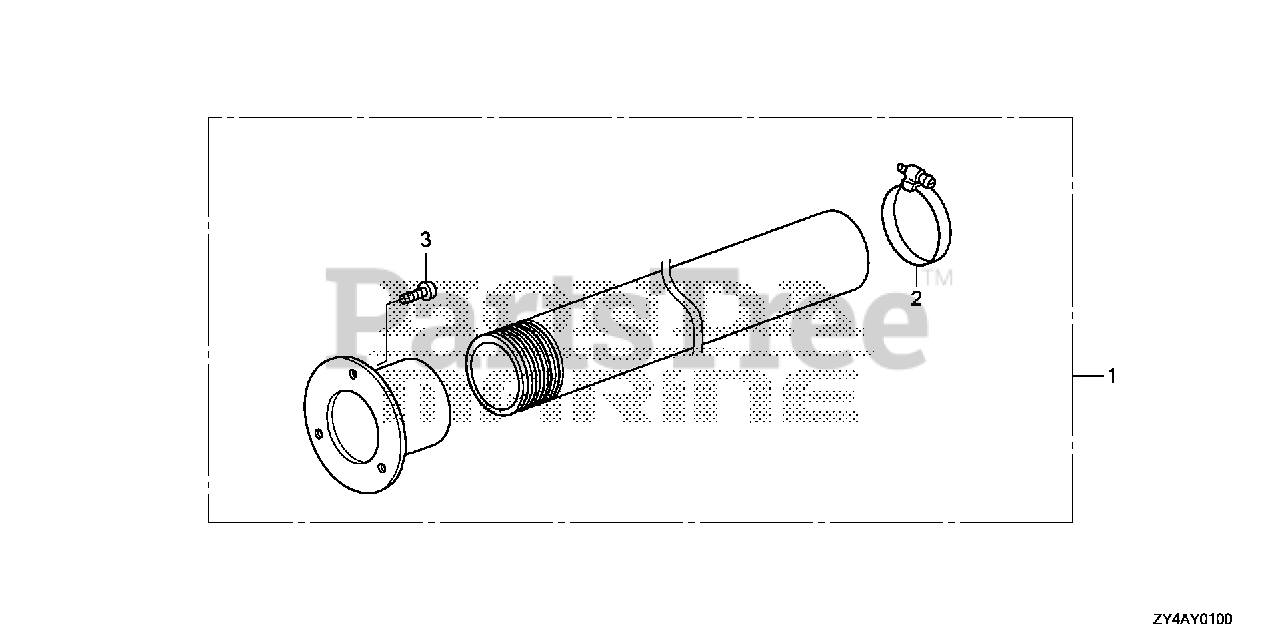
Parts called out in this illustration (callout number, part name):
1	HOSE KIT, RIGGING
2	CLAMP
3	SCREW, TAPPING
